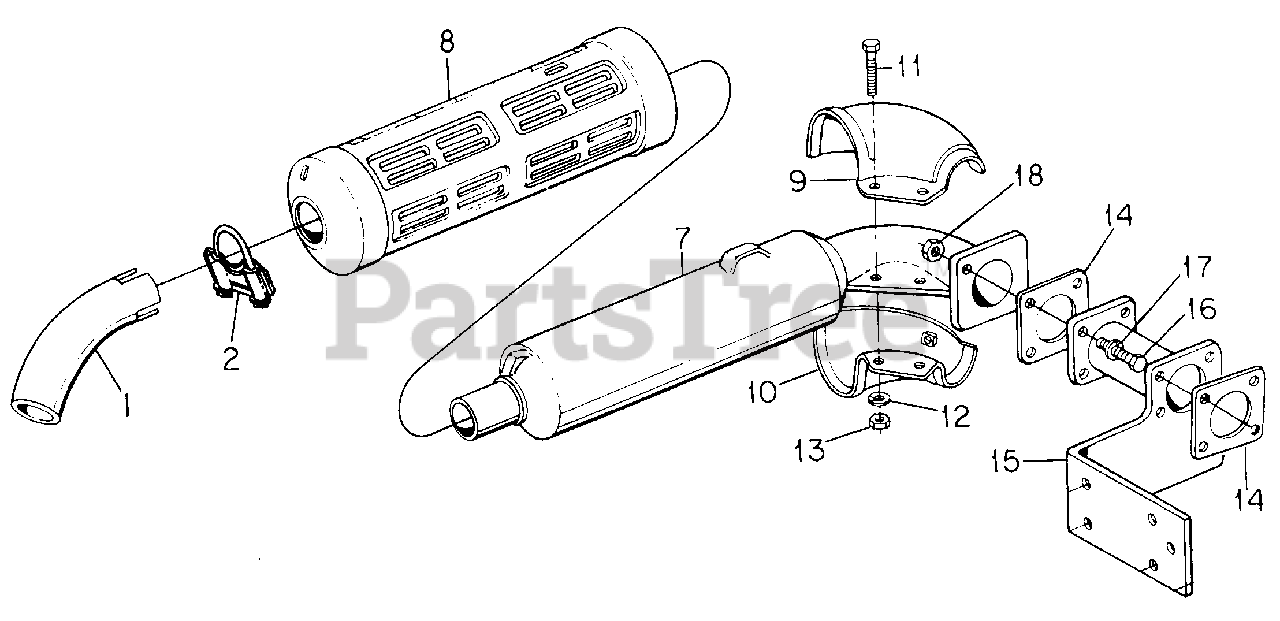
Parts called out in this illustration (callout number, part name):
1	Pipe, Muffler
8	Cover w/Product Graphic
9	Cover, Muffler Flange, LH
10	Cover, Muffler Flange, RH
11	Bolt, M6 X 28-8.8
12	Washer, 6MM Lock
13	Nut, M6 Znd Class 8
14	Gasket, Muffler
15	Extension, Exhaust Manifold
16	Bolt, 5/16-NF X 1 Type 5
17	Washer, 5/16 Lock
18	Nut, 5/16-NF Type 5
